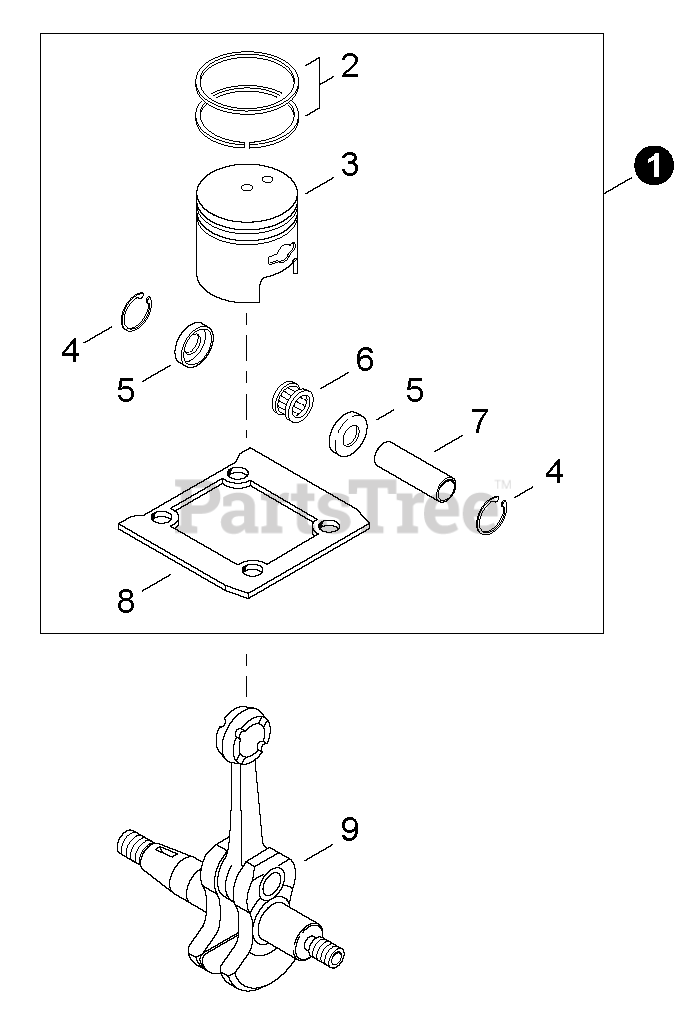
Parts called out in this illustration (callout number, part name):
1	PISTON KIT
2	RING, PISTON
3	PISTON
4	RING, SNAP
5	WASHER, THRUST 11
6	BEARING, NEEDLE 11
7	PIN, PISTON 11
8	GASKET, CYLINDER
9	CRANKSHAFT ASSY
